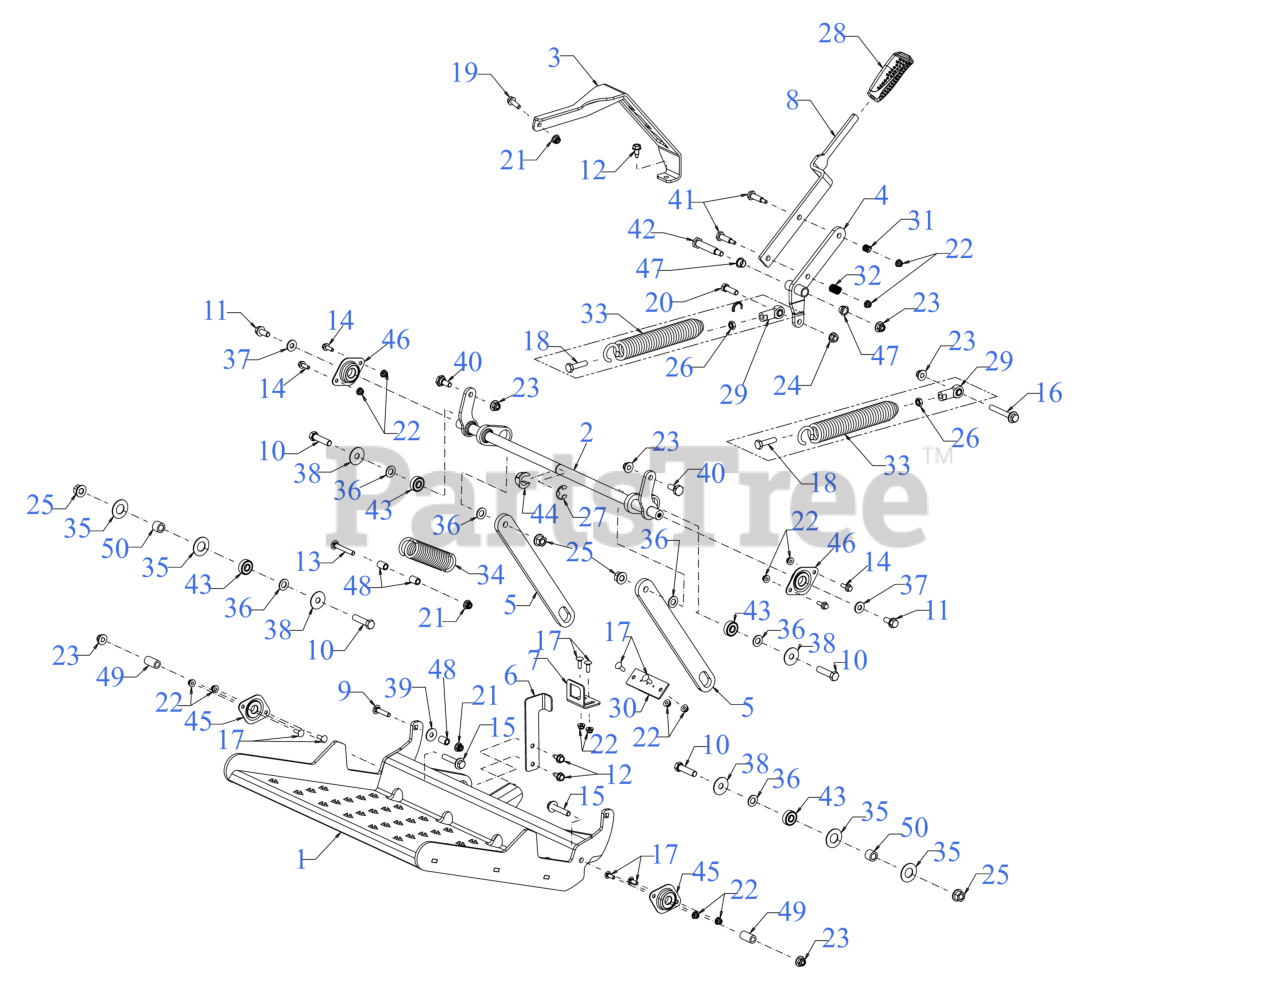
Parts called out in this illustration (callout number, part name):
1	PLATFORM ASSEMBLY
2	ROLLER LINK
3	ADJUSTMENT INDEX
4	ADJUSTMENT ARM
5	SUSPENSION LINK
6	SWITCH BRACKET
7	SWITCH BRACKET MOUNT
8	ADJUSTMENT SPRING LEVER
9	CARRIAGE BOLT 5/16-18 x 1.50
10	SCREW 7/16-20 x 1.75 GR 5
11	SCREW 3/8-16 x .875 GR5
12	SCREW 5/16-18 x .750
13	BOLT 5/16-18 x 2.50 GR1
14	SCREW 1/4-20 x .75 GR5
15	SCREW 3/8-16 x 2.0
16	SCREW 3/8-16 x 2.75 GR5
17	SCREW 1/4-20 x .75 GR5
18	SCREW 3/8-24 x 1.50 GR8
19	SCREW 5/16-18 x .875 GR5
20	SCREW 3/8-16 x 1.25 GR5
21	FLANGE LOCK NUT 5/16-18
22	FLANGE LOCK NUT
24	HEX LOCK NUT
25	FLANGE LOCK NUT
26	HEX JAM NUT 3/8X24
27	E-RING
29	ROD END 3/8 ID
30	SUSPENSION BUMPER
31	COMPRESSION SPRING
32	COMPRESSION SPRING
33	ADJUSTMENT SPRING
34	EXTENSION SPRING 1.478 x 5.729
35	FLAT WASHER .760ID X1.49OD x .06
36	FLAT WASHER
37	FLAT WASHER .385X.870X.090
38	FLAT WASHER
39	FLAT WASHER 344X1.00
40	SHOULDER SCREW
41	SHOULDER SCREW
42	SHOULDER SCREW .50 x 2.23 3/8-16
43	BALL BEARING
44	HEX FLANGE SPLIT BEARING
45	BALL BEARING
46	BALL BEARING
47	NYLINER BEARING
48	SLEEVE .33X.50X.75 LG
49	SPACER .380x.624x1.040
50	SPACER .465x.760x.550
